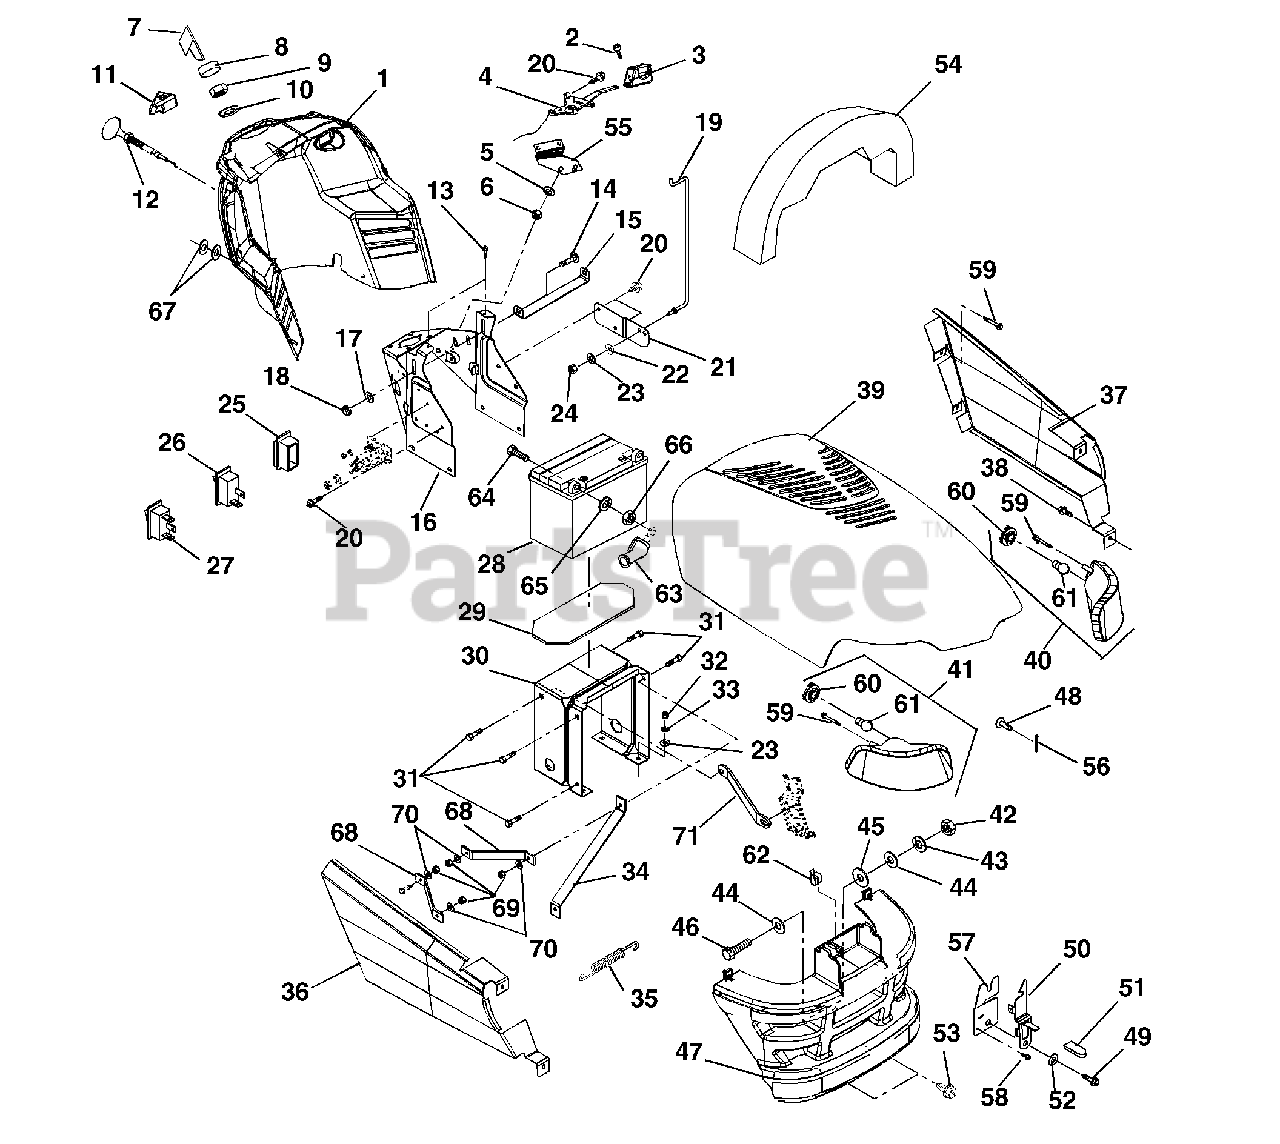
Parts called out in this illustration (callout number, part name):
1	DASH-VENTED
2	SCR-SET 10-24X.38 UNC-3A
3	KNOB, THROTTLE
4	THROTTLE CONTROL- TEC/B&S
5	WSHR-FL-STL .323X.625X.062 YWZ
6	@NUT-LK-CTR .25-20 YWZC
7	IGNITION SWITCH KEY
8	CAP - IGNITION SWITCH
9	NUT- PANEL .562-24 GRECO
10	WSHR-LK-INT .625X.045 YWZC
11	PTO SWITCH ASSEMBLY
12	CHOKE CABLE
13	SCR-TAP 10-24X.484 HWH TR
14	@BLT-RDHDSQNK .31-18X.75 G5YZ
15	HOLDDOWN - BATTERY
16	SUPPORT - DASH - TOP
17	WSHR-FL-STL .323X.625X.062 YWZ
18	@NUT-LK-NYL .312-18 YWZC
19	ROD - HOOD PROP
20	@SCR-TAP .25-20X.37 HWH YWZ TR
21	MOUNT - PROP ROD
22	WAVE WASHER .390X.655X.110
23	@WSHR-FL-STL.312X.734X.065 YWZ
24	@NUT-LK-CTR .25-20 YWZC
25	COVER - SWITCH
26	SWITCH - LIGHT
27	SWITCH - CRUISE
28	BATTERY W/TUBE
29	RUBBER PAD
30	SUPPORT DASH BASE
31	@SCR-TAP .31-18X.50 HWH TR YWZ
32	@NUT-HEX .31-18 YWZC
33	WSHR-LK .312X.097 HVY YWZC
35	SG-TENS .035X.45X2.75 WLD 3.5
36	PANEL, R.H
37	PANEL, L.H
38	SCR-TAP 12-16X.500 HI-LOTPHBL
39	HOOD, ARIENS W/SLOTS
39	HOOD - ARIENS
40	HEADLIGHT- LH
41	HEADLIGHT- RH
42	@NUT-HEX .31-18 YWZC
43	WSHR-LK .312X.097 HVY YWZC
44	WSHR-FL-STL .328X1.0X.094 YWZC
45	WSHR-FL-NYL .390X1.000X.062
46	@BLT-HEX .31-18X1.00 GR5 YWZC
48	PIN, CLEVIS .243/.248X1.50 YWZ
49	SCR-TAP 12-24X.50 HWH TR BLACK
50	HOOD LATCH
51	GRIP .062 X .375 X 1.000 RE
52	WSHR-FL-STL .281X1.250X.048 BL
53	SCR-TAP .312-18X.50 HWH TR BL
54	BAFFLE, FOAM (INTEK V TWIN)
54	BAFFLE- HOOD
54	BAFFLE, HOOD
55	BRACE-THROTTLE CONTROL
56	@PIN-CTR .09X.75 EXTPRSQCT YWZ
57	LOCATOR- HOOD
58	SCR-TAP 10-12X.50 CRPH PL A BL
59	SCR-TAP 10-24X.75 HWH TR YWZC
60	LAMP SOCKET
61	HEADLIGHT BULB, 1156
62	CLIP-HARNESS TINNERMAN
63	INSULATOR
64	@BLT-HEX .25-20X.75 GR5 YWZC
65	WSHR-LK .250X.077 HVY YWZC
66	@NUT-HEX .25-20 YWZC
67	WSHR-FL-STL .219X.500X.049BLZC
68	BRACKET-STEERING ASSEMBLY
69	@NUT-LK-NYL .312-18 YWZC
70	@WSHR-FL-STL.344X.688X.065YWZC
71	BRACKET-STEERING ASSEMBLY
